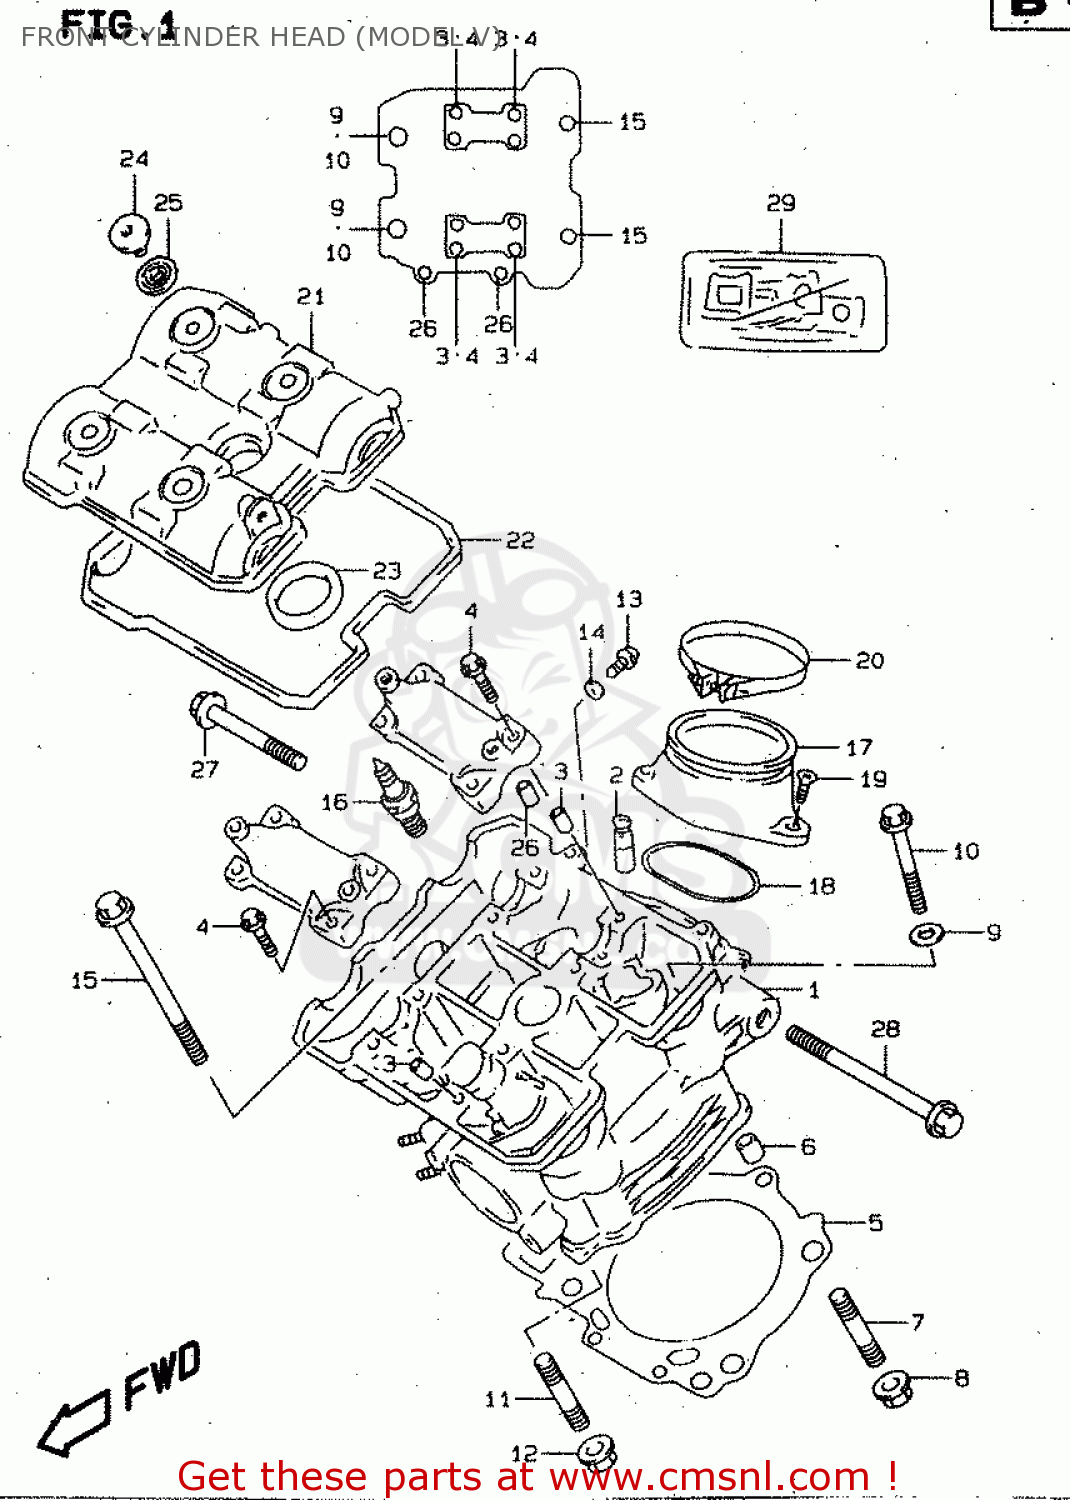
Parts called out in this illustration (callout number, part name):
1	HEAD ASSEMBLY,CYLINDER
2	GUIDE,VALVE
3	PIN(6.2X8X11)
4	BOLT(6X39)
5	GASKET,CYLINDER HEAD,FRONT (NAS)
6	PIN
7	BOLT,STUD
8	NUT
9	WASHER(10.5X19X2)
10	BOLT(10X175)
11	BOLT,STUD
12	NUT
13	BOLT
14	GASKET(5.8X13X1.2) (NAS)
15	BOLT(6X70)
16	PLUG,SPARK(CR8E)
17	PIPE ASSY,INTAKE
18	O RING(D:2.4,ID:55.6)
19	SCREW
20	CLAMP
21	COVER,CYLINDER HEAD FR
22	GASKET,CYL HEAD COVER NO.1 (NAS)
23	GASKET,CYL HEAD COVER NO.2
24	BOLT(7X17.5)
25	WASHER(10.6X25.5X2.3)
26	PIN(6.2X8X11)
27	BOLT
28	BOLT
29	GASKET SET (NAS)
